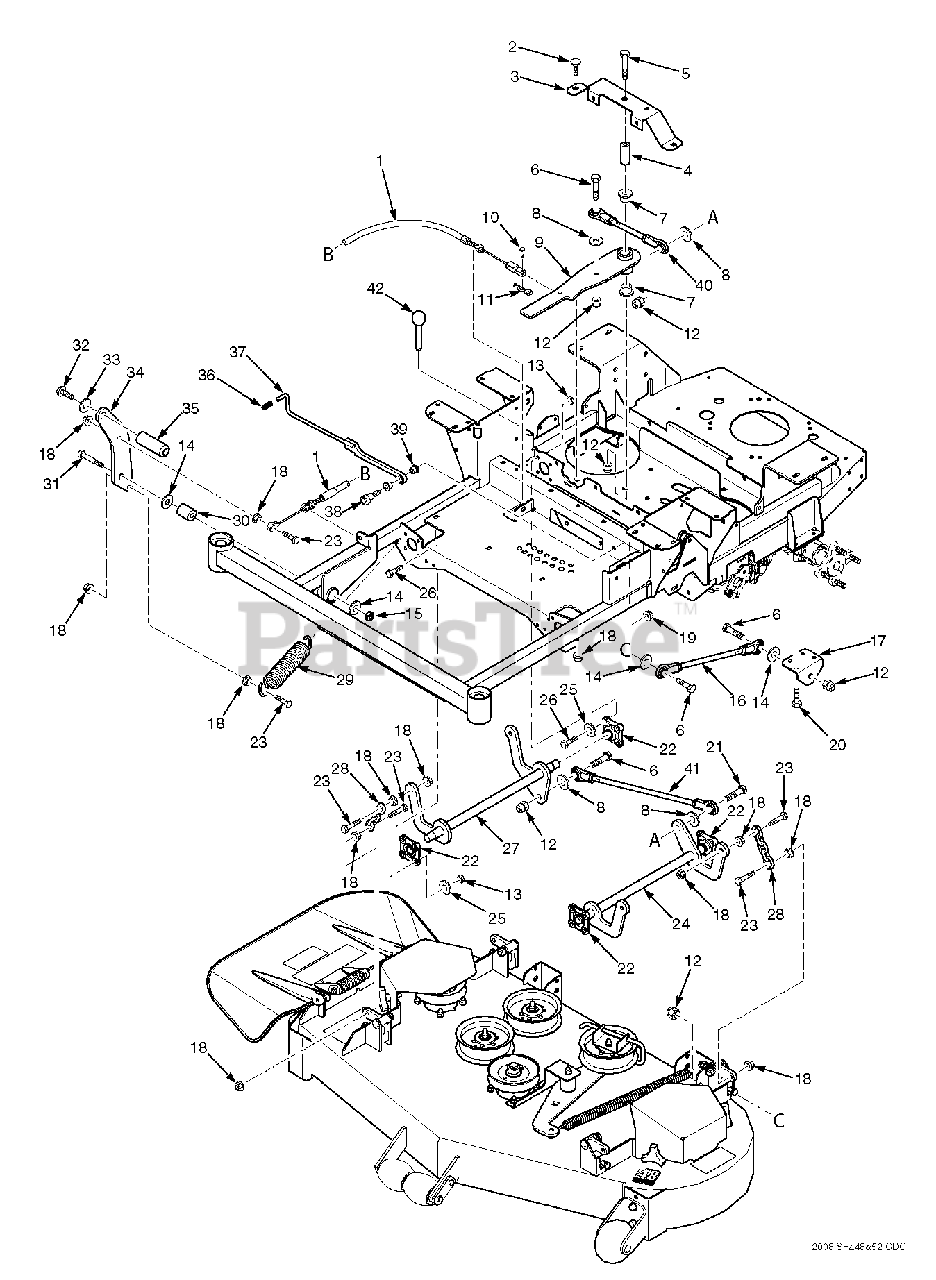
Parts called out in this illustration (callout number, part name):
1	Cable, Deck Lift
2	Bolt, Carriage 3/8-16 x 3/4"
3	Support, Idler Arm
4	Spacer, Deck Lift Pivot
5	Bolt, Hex Head 1/2-13 x 3-3/4"
6	Bolt, Hex Head 1/2-13 x 1-3/4"
7	Bearing
8	Flatwasher, 1/2-.531 x 1.06 x .095
9	Deck Lift Bellcrank Assembly
10	Clevis Pin, 5/16 x 3/4"
11	Hair Pin, .094 x 1.62"
12	Nut, Elastic Stop 1/2-13
13	Nut, Elastic Stop 5/16-18
14	Flatwasher, 1/2-.562 x 1.375 x .109
15	Nut, Center Lock 1/2-13
16	Linkage, Push Arm
17	Bracket, Push Arm Link
18	Nut, Serrated Flange 3/8-16
19	Nut, Elastic Stop 3/8-16
20	Bolt, Hex Head 5/16-18 x 3"
21	Bolt, Hex Head 1/2-13 x 2-1/2"
22	Bearing, Deck Lift
23	Bolt, Hex Head 3/8-16 x 1-1/2"
24	Weldment, Deck Lift LH
25	Flatwasher, 1/4-.312 x .750 x .065
26	Bolt, Hex Head 5/16-18 x 1"
27	Weldment, Deck Lift RH
28	Chain, Deck lift
29	Spring, Deck Lift
30	Sleeve, Deck Lift Pivot
31	Bolt, Hex Head 1/2-13 x 3"
32	Bolt, Head Socket 5/8-11 x 1-1/2"
33	Lockwasher, 5/8 Spring
34	Pedal, Foot Bracket
35	Foot Pedal
36	Grip, Deck Latch
37	Weldment, Deck Latch
38	Bolt, Shoulder 1/2 x 1/2
39	Bearing
40	Linkage Assembly, Deck Lift
41	Linkage Assembly, Deck Lift
42	Pin, Height Adjuster
